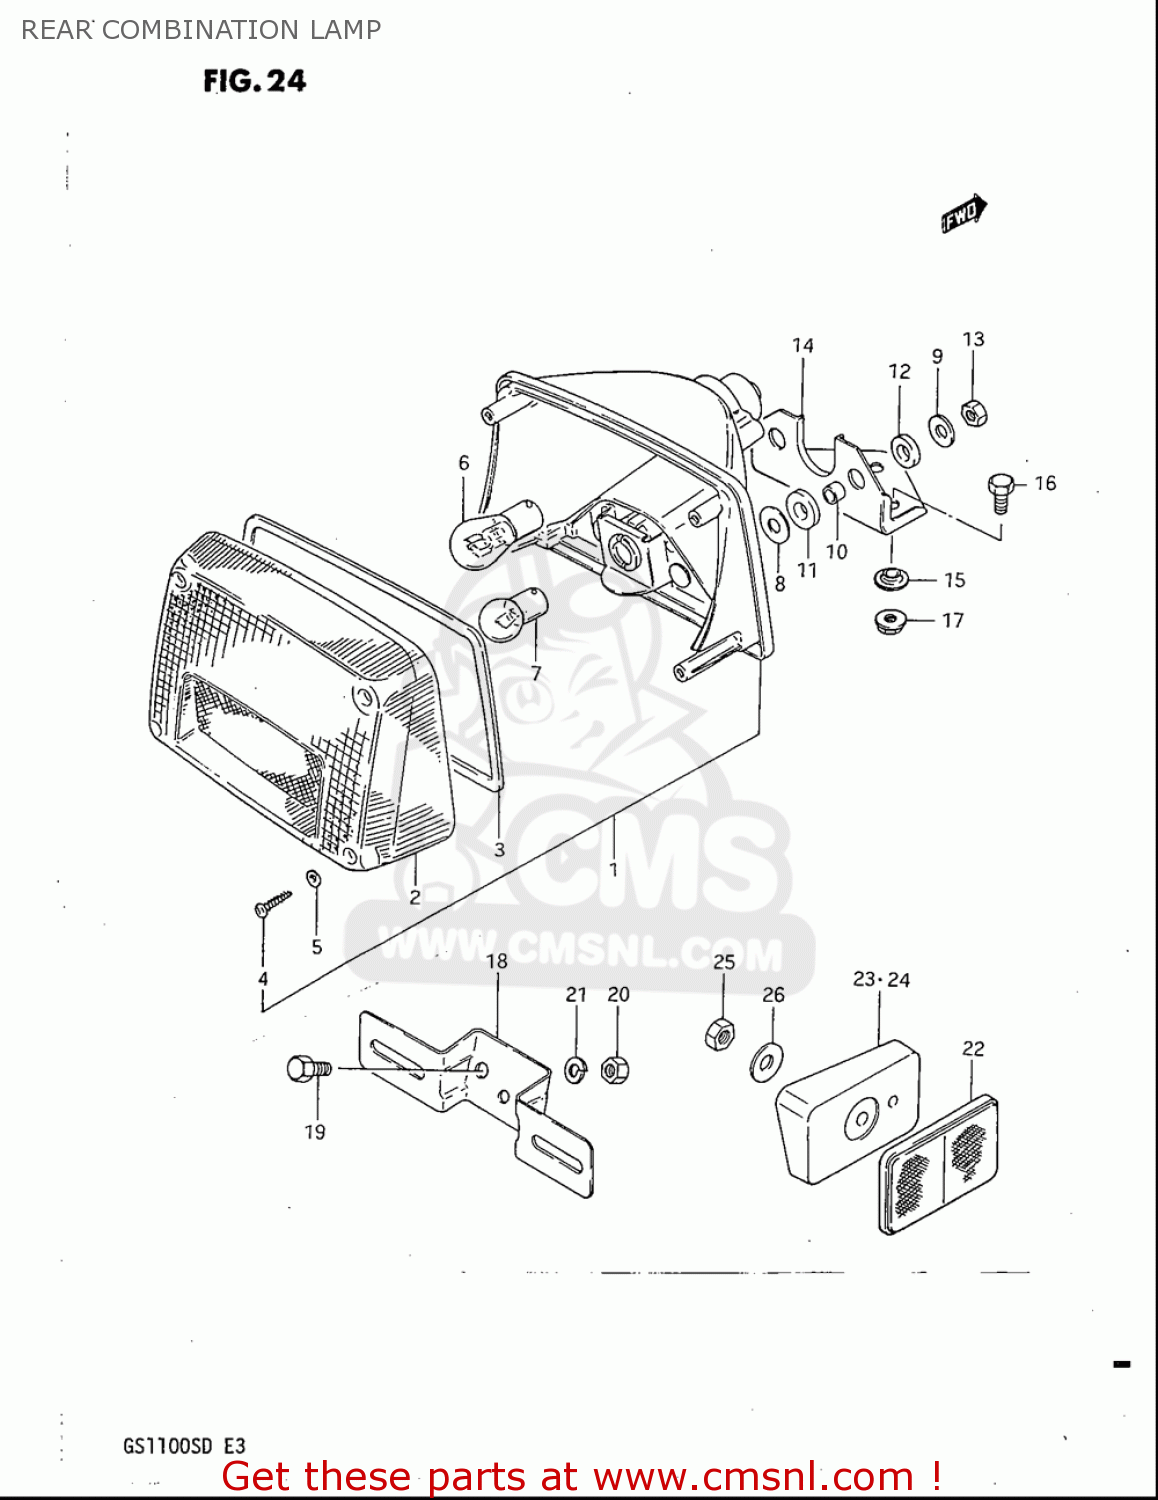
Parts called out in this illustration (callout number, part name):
1	LAMP ASSY,RR COMBINATION
2	LENS
3	GASKET (NAS)
4	SCREW
5	GASKET (NAS)
6	BULB(12V23W)
7	BULB(12V8W)
8	WASHER(6.5X18X1.6)
9	WASHER(6.5X22X1.6)
10	SPACER(6.1X9X7.5)
11	CUSHION
12	CUSHION
13	NUT
15	WASHER
16	BOLT
17	NUT
19	BOLT
20	NUT
21	WASHER,LOCK
22	REFLEX REFLECTOR,RR
25	NUT
26	WASHER
